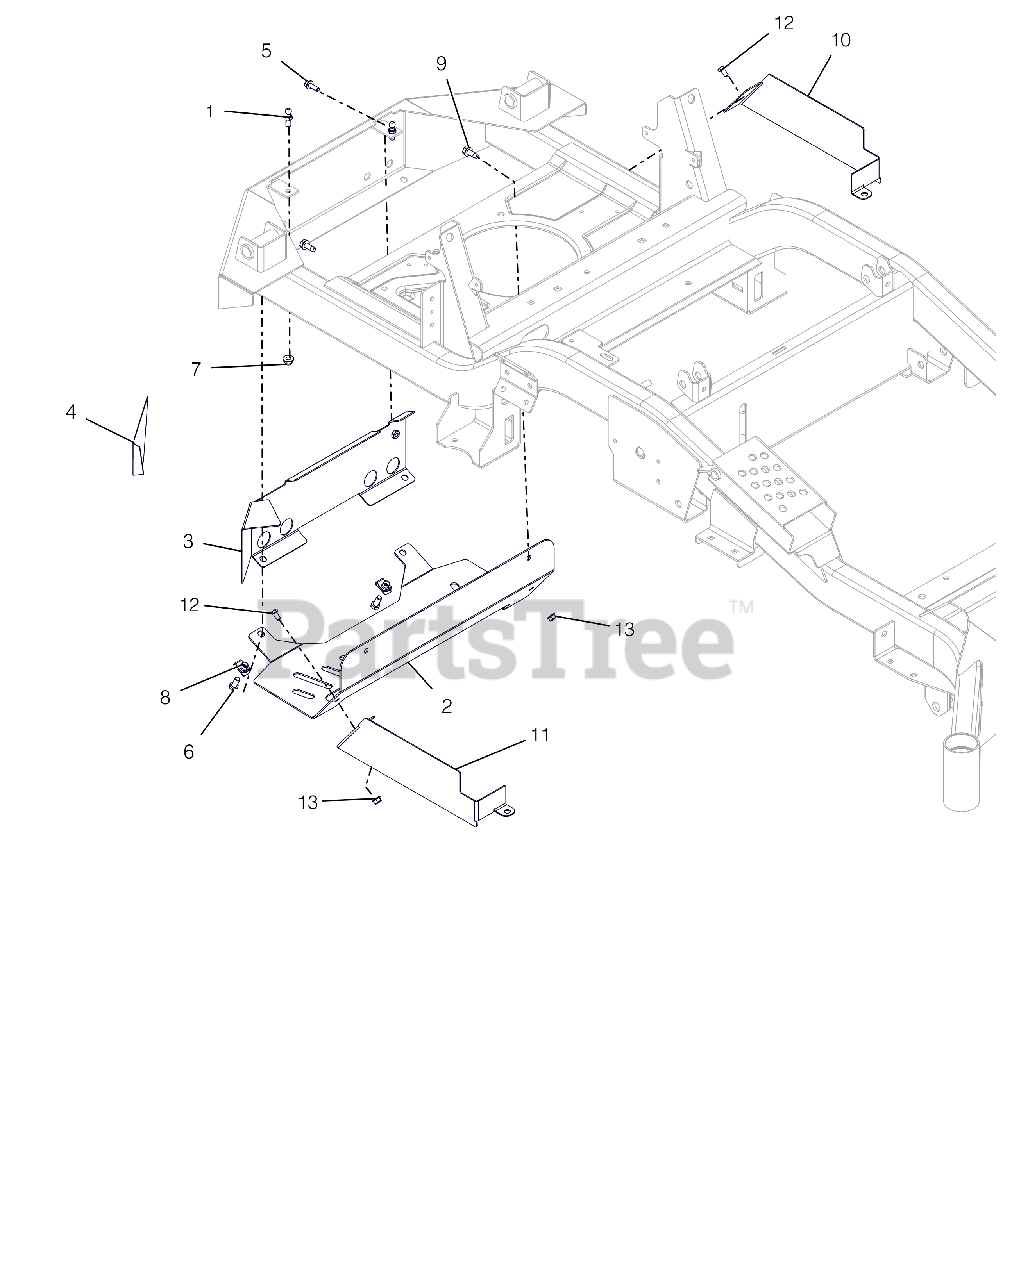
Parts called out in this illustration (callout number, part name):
1	STUD- BALL
2	SHIELD, HEAT (HD)
3	WMT, HEAT BAFFLE
4	TAPE, HEAT DEFLECTOR
5	BLT,HEX-FLG .25-20X.75 G5 BFP
6	@BLT-HEX .31-18X.75 GR5 YWZC
7	NUT,LK-NYL-FLG .31-18 G5ZC120
8	NUT-CLIP RETAINER 5/16-18X.56
9	@SCR-TAP .31-18X.75 HWH TR YWZ
10	GUARD,REAR CLUTCH LH
11	GUARD,REAR CLUTCH RH
12	@BLT-HEX .25-20X.50 GR5 YWZC
13	@NUT-LK-TOP-FLG .25-20 YWZC
